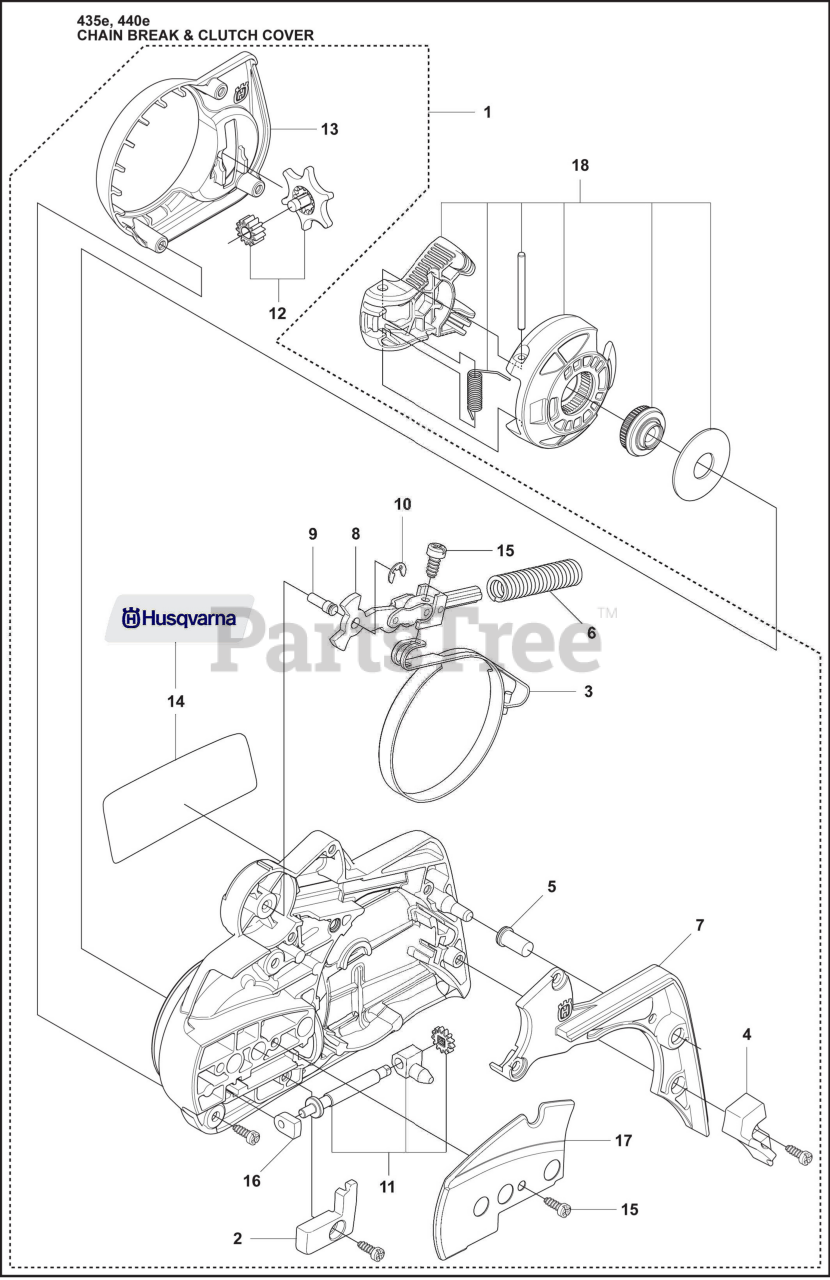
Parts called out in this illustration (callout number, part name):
1	Chain Brake Assembly, Husq Orange
2	Cover
3	Brake Band Assembly
4	Wear Protection
5	Sleeve
6	Brake Spring
7	Cover
8	Joint
9	Pin
10	Bar Retainer
11	Chain Tensioner Screw, Comp
12	Chain Tensioner Wheel
13	Heat Shield
14	Clutch Housing Decal
15	Screw
16	Sleeve Bearing
17	Plate
18	Complete Knob
